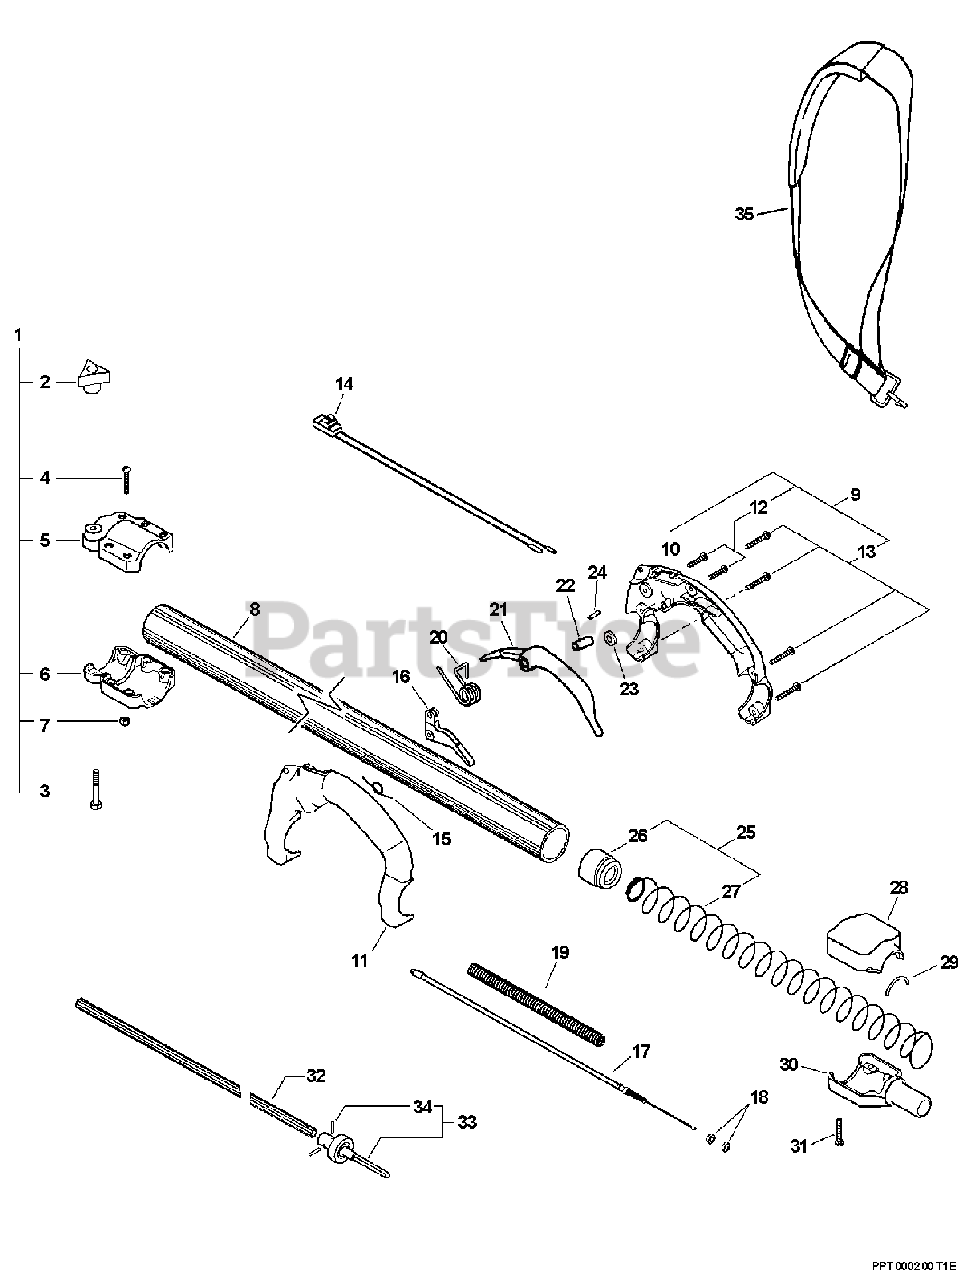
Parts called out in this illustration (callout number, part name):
1	CLAMP ASSY
2	THUMBSCREW
3	SCREW
4	SCREW, TORX 10-24 UNC 1-1/4
5	COLLAR, UPPER
6	COLLAR, LOWER
7	NUT, LOCK 10-24 UNC
8	PIPE, MAIN 1.5 ID×60" L
9	REAR HANDLE ASSY
10	HANDLE, REAR - RIGHT
11	HANDLE, REAR - LEFT
12	SCREW, TORX
13	SCREW, TORX 10-24 UNC 1-1/4
14	SWITCH ASSY, ON-OFF
15	SPRING, TORSION
16	TRIGGER, THROTTLE
17	CABLE, THROTTLE
19	TUBE, FLEXIBLE
20	SPRING, TORSION Ø0.39 I.D.
21	LOCKOUT, THROTTLE
22	COLLAR 5.08×14.5
23	WASHER 5.5×12×0.8
24	PIN, LOCATING 0.17 OD×0.75 L
25	BUSHING ASSY, FLOATING
26	BUSHING, FLOATING
27	SPRING, COMPRESSION
28	CAP, MAIN PIPE
30	COUPLING, MAIN PIPE
31	SCREW, TORX 10-24 UNC 1-1/4
32	DRIVESHAFT
33	SHAFT CONNECTOR KIT
34	PIN 0.098"×0.687"
35	STRAP ASSY, SHOULDER
